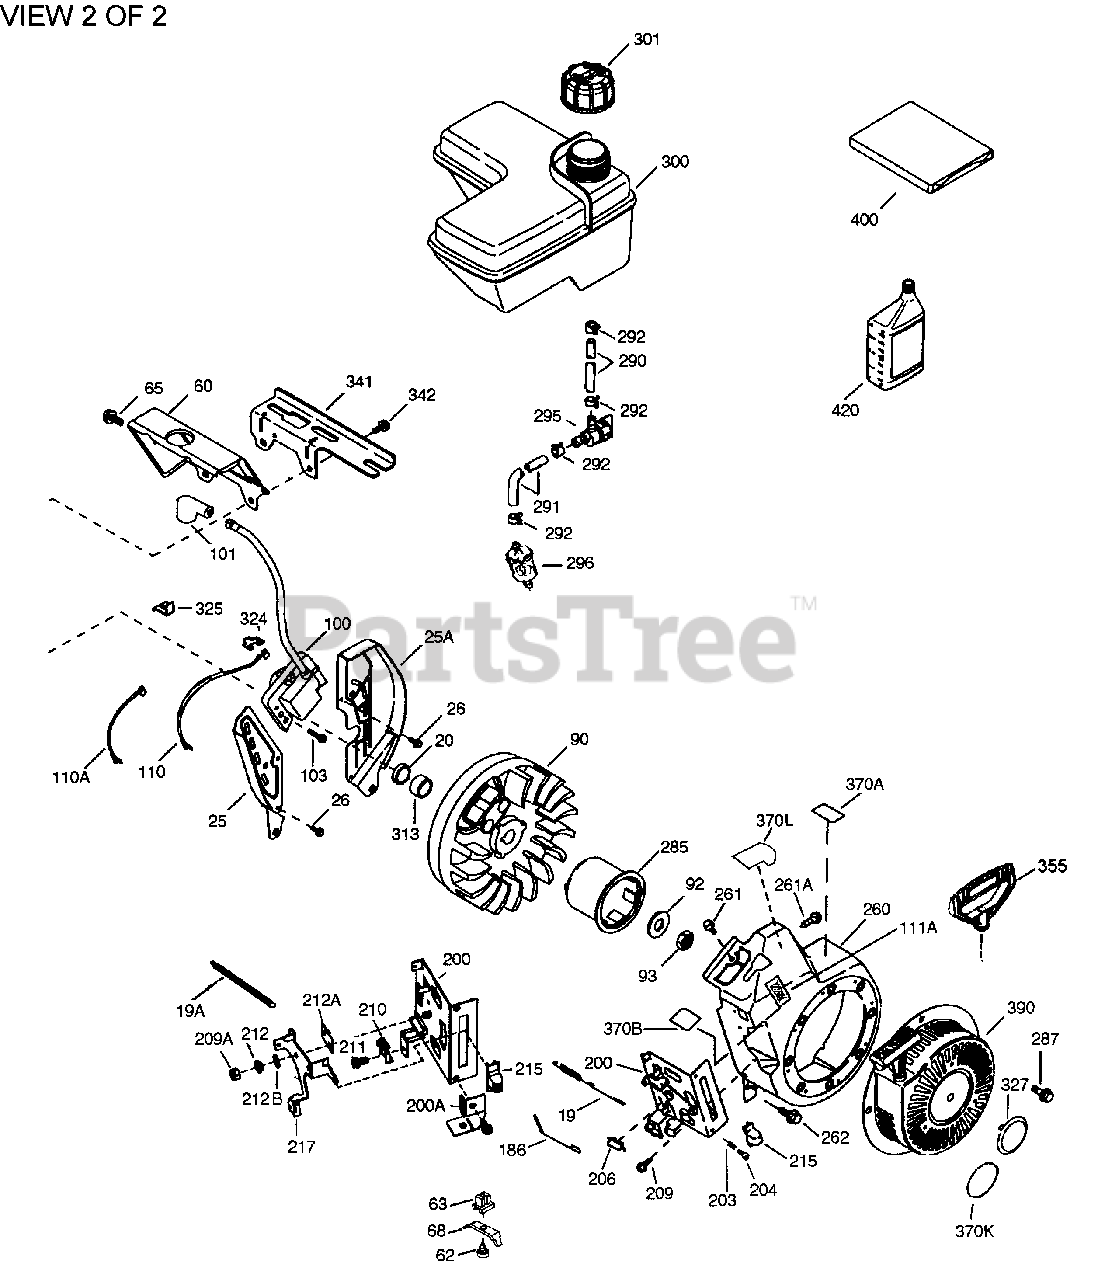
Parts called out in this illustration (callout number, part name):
19	Extension Spring
20	Oil Seal
25	Air Baffle (Left)
25A	Air Baffle (Right)
26	Screw, 10-24 x 9/16"
60	Blower Housing Extension
65	Screw, 10-24 x 9/16"
90	Flywheel
92	Belleville Washer
93	Flywheel Nut
100	Solid State Ignition
101	Spark Plug Cover
103	Screw, Torx T-15, 10-24 x 15/16"
110	Ground Wire
186	Governor Link
200	Control Bracket (Incl. 206 & 215)
206	Terminal
209	Screw, 10-32 x 1/2"
215	Control Knob
260	Blower Housing
261	Screw, 1/4-20 x 31/64"
261A	Screw, 10-32 x 1/2"
262	Screw, 1/4-20 x 31/64"
285	Starter Cup
287	Rivet (Can be purchased locally)
290	Fuel Line
292	Fuel Line Clamp
300	Fuel Tank (Incl. 301)
301	Fuel Cap
325	Wire Clip
327	Starter Plug
341	Fuel Tank Bracket
342	Screw, 1/4-20 x 7/8"
370A	Lubrication Decal
370B	Speed Control Decal
390	Rewind Starter
400	* Gasket Set (Incl. items marked PK in notes) Incl. (1) each of 26756,27272A , 29673, 35626, 36581, 36624,36738
999	Summer Maintenance Kit (incl. Oil, Sp ark Plug, Air Cleaner, & Ultra Fresh)
